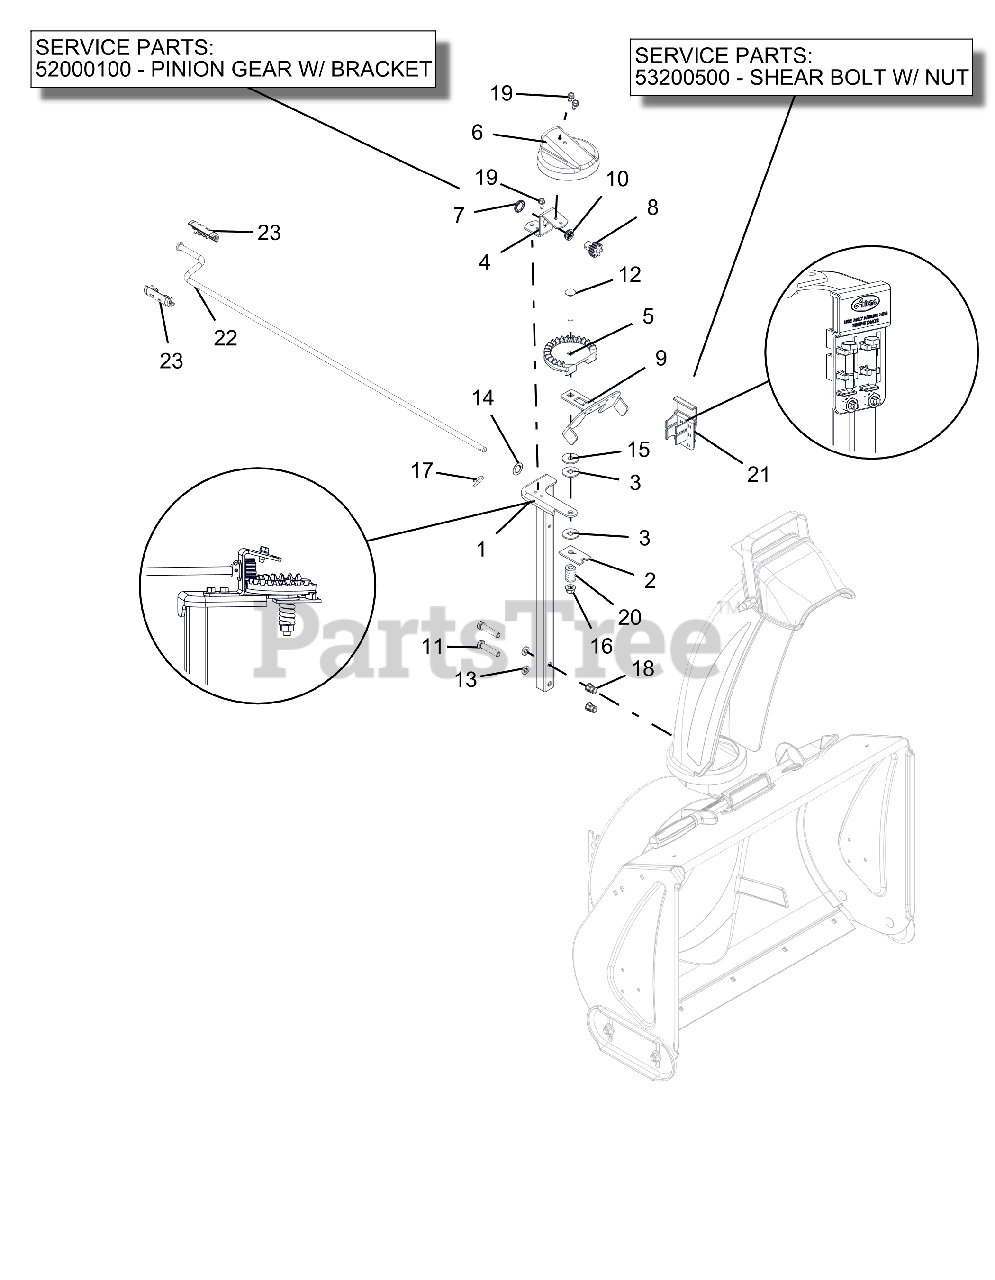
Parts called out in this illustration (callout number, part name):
1	CHUTE PEDESTAL, TALL COMPACT
2	PLATE, FRICTION
3	FRICTION WASHER
4	BRACKET, PINION GEAR
5	CHUTE GEAR
6	GEAR COVER
7	PUSHNUT .625
8	PINION GEAR - CHUTE
9	CHUTE MOUNT BRACKET
10	BUSHING, POLYLINER-.63 SNAPIN
11	@BLT-HEX .38-16X1.75 GR5 YWZC
12	@BLT-RDHDSQNK .38-16X2.50 G5YZ
13	@WSHR-LK .38X.094 REG YWZC
14	WSHR-THRST .625 X 1.0 X .03
15	@WSHR-FL-STL .406X1.25X.10 ZC
16	@NUT-LK-TOP-FLG .38-16 YWZC
17	PIN, SPRING CLIP
18	NUT, THREADED INSERT .38-16
19	SCR-TAP .25-20X.50 HWH TR YWZ
20	SG-COMP .187X.56X1.62
21	HOLDER W SMALL SHEAR BOLT /NUT
21	SHEAR BOLT WITH NUT
22	ROD, CHUTE CRANK, COMP&SNOTEK
23	KNOB, CHUTE CRANK - SNAP BLK
24	PINION GEAR W/BRACKET
